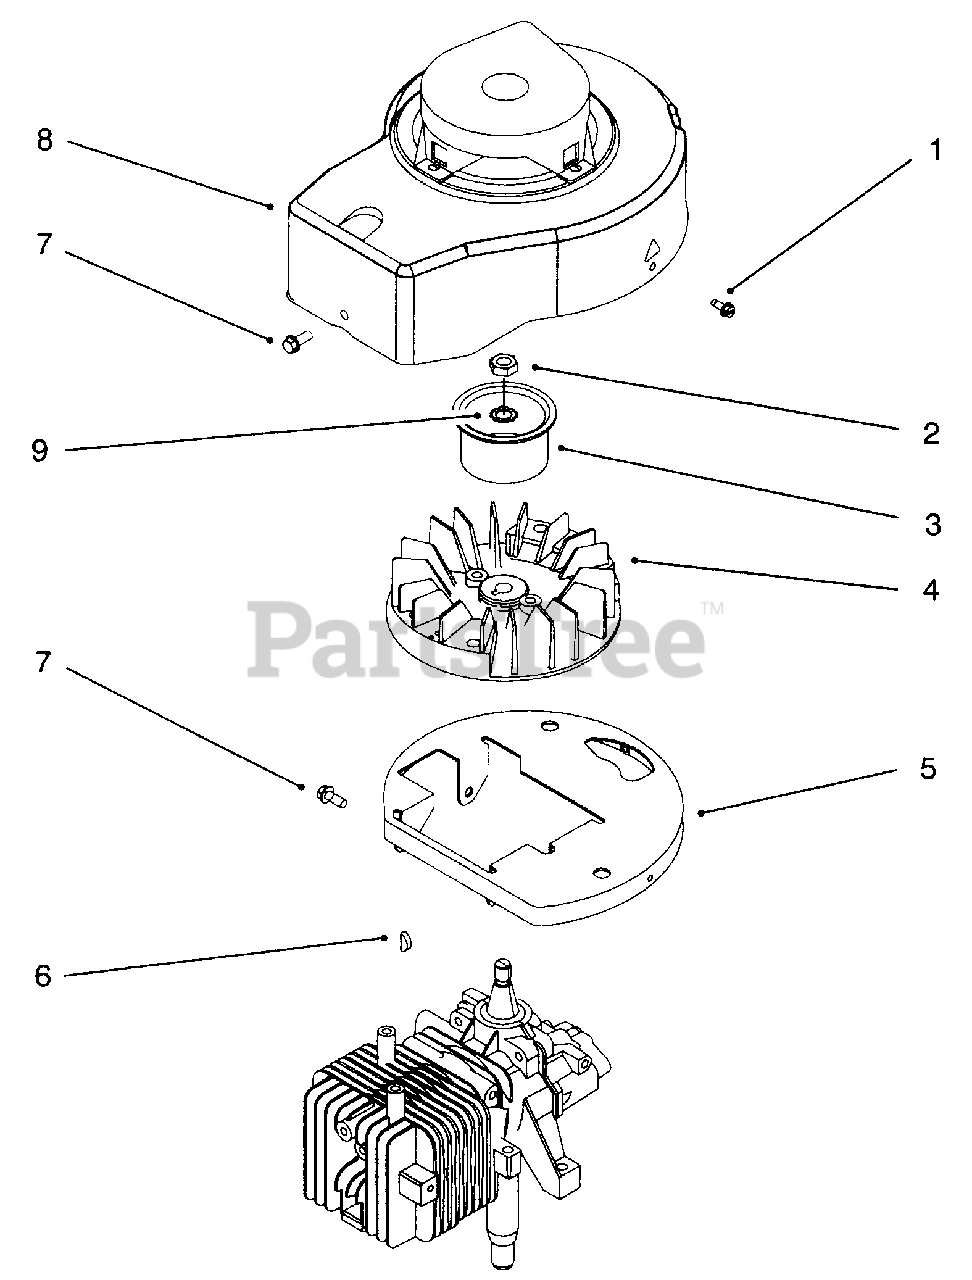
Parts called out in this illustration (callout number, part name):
3	Hub-Starter
4	Flywheel
5	Base-Shroud
7	Screw
8	Shroud Assembly
9	Washer-Lock
